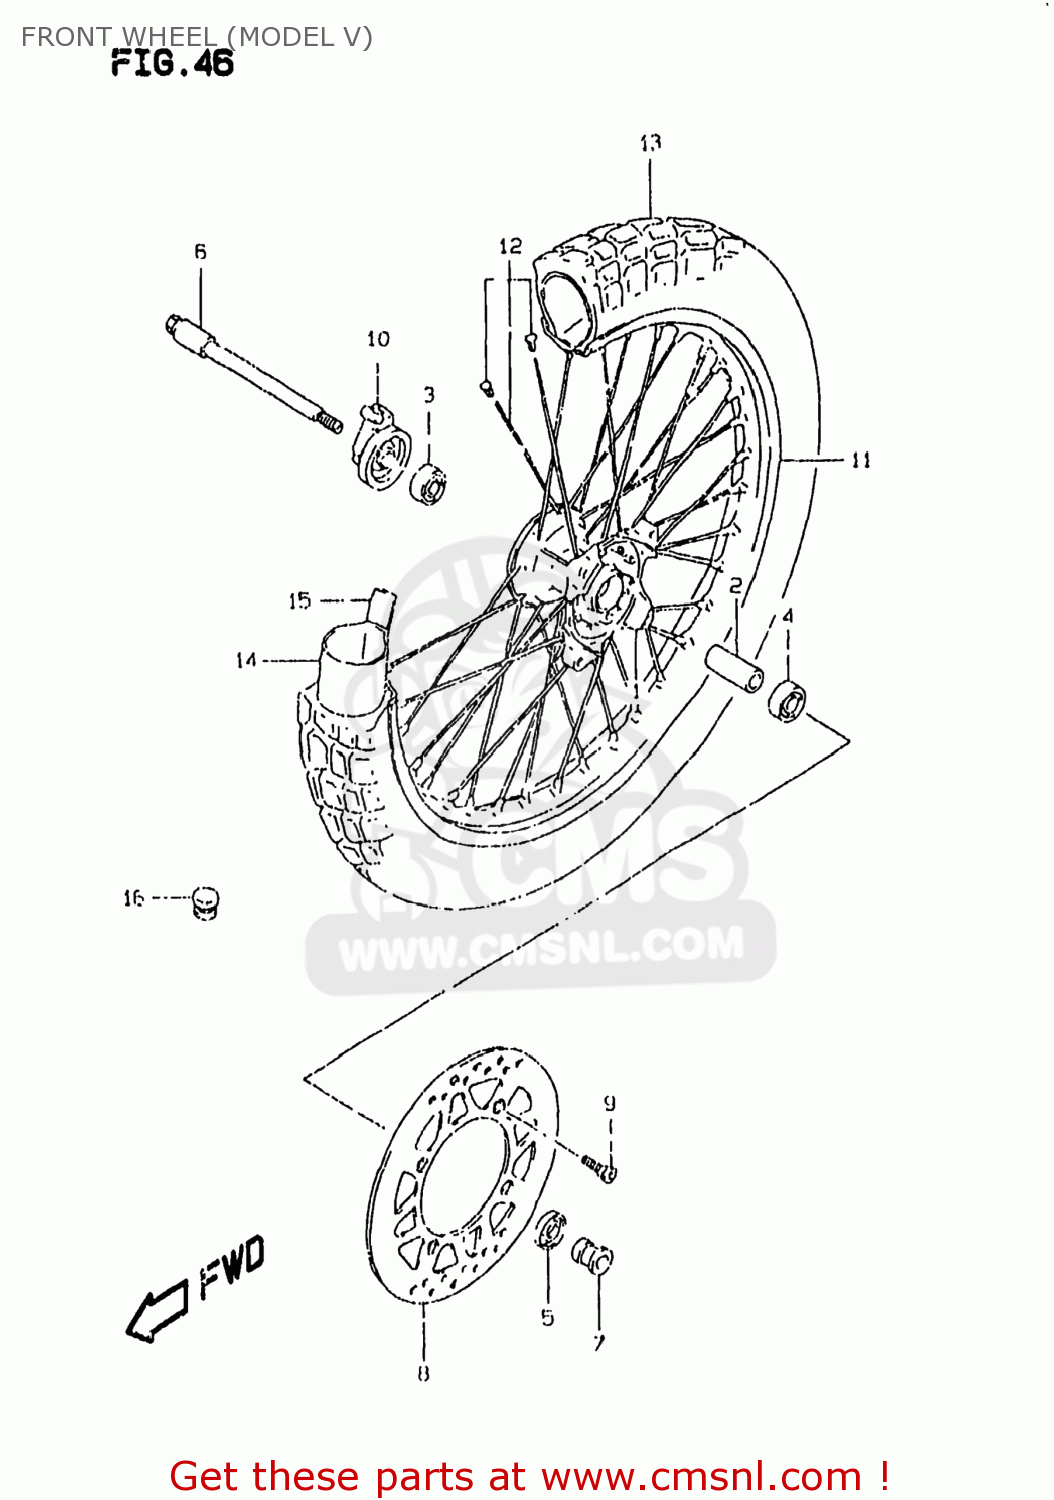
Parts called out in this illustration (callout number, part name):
1	HUB,FR WHEEL
2	SPACER,FR HUB BEARING
3	BEARING
4	BEARING
5	SEAL,OIL(22X35X5)
6	AXLE,FR
7	SPACER,FR AXLE,L
8	DISC,FR BRAKE
9	BOLT,BRAKE DISC
10	BOX ASSY,SPEEDOMETER GEAR
11	RIM,FR WHEEL(1.60X21)
12	SPOKE SET,FR WHEEL
13	TIRE,FR(80/100 21)
14	TUBE
15	PROTECTOR,WHEEL INNER
16	CAP(OD:12)
